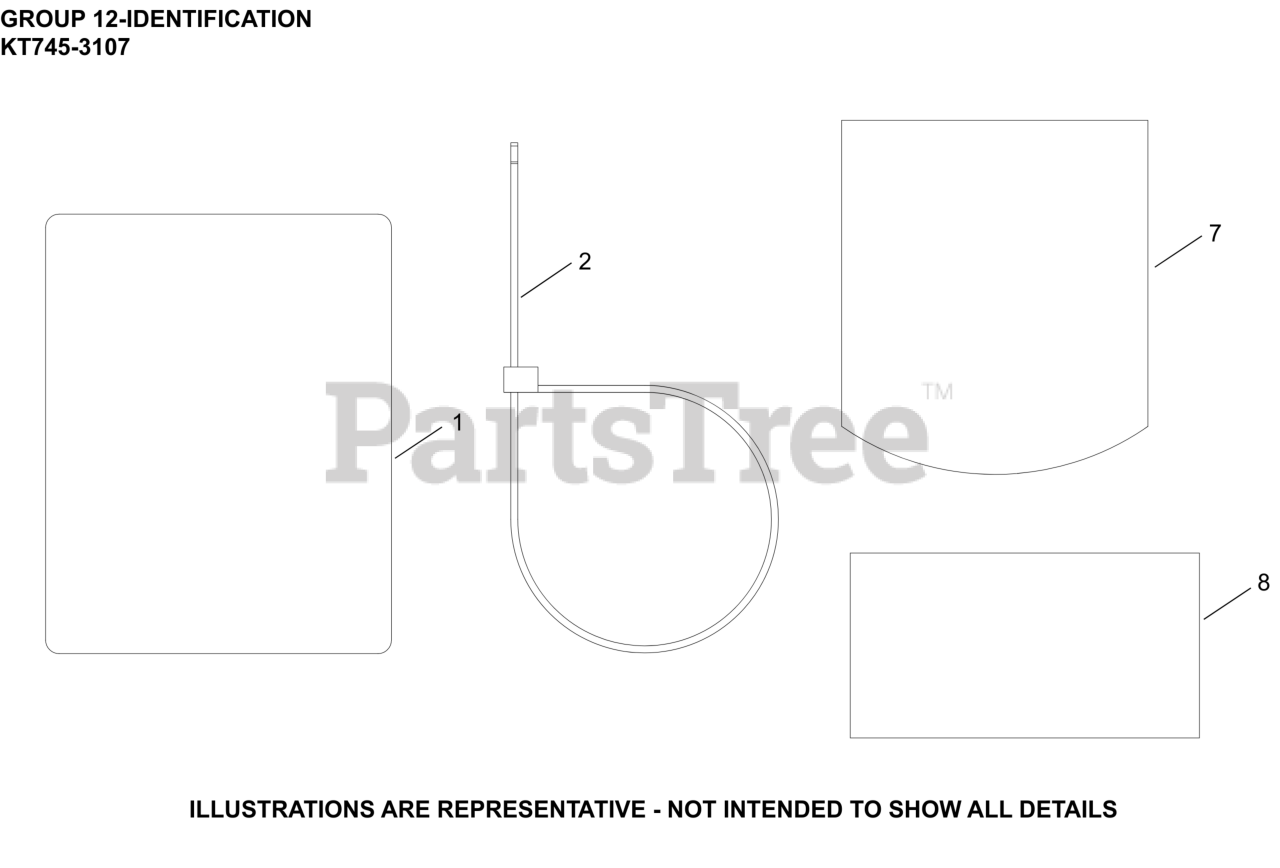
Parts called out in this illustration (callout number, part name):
1	LABEL, CLEAR LAMINATION
7	LABEL, 7000 SERIES KT745 (26 HP,PRO A/F)
8	DECAL, USA
